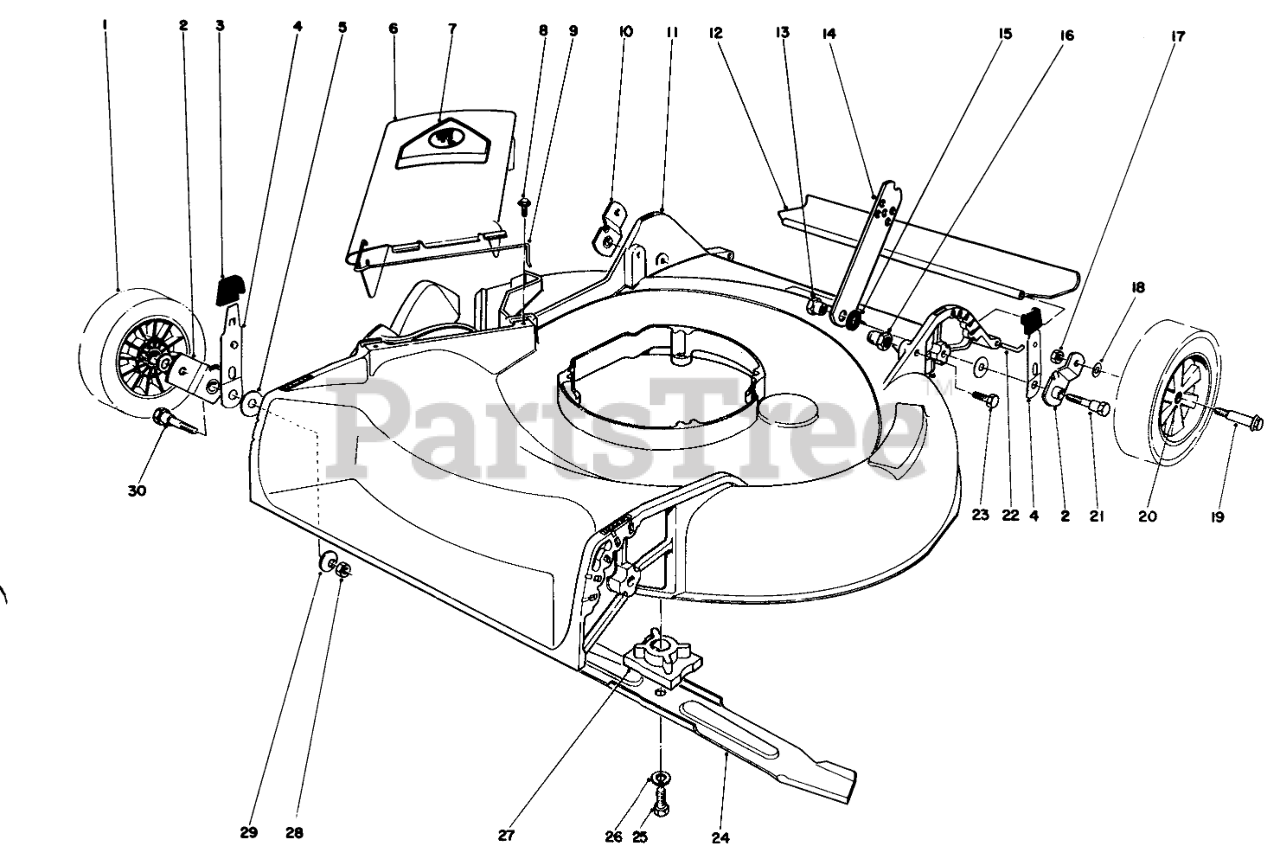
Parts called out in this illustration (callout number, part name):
1	Wheel & Tire Assembly (Incl. Ref. #20)
2	Pivot Arm
3	KNOB-ARM
4	SPRING ARM ASM
5	WASHER-PIVOT
6	Deflector Assembly (Incl. Ref. #7 & 9)
7	DECAL-DANGER
8	SCREW-HWH
9	SPRING HINGE
10	Pivot Arm
11	HOUSING/DECAL
12	REAR SAFETY SHIELD 21
13	HANDLE PIVOT NUT
14	HANDLE LATCH
15	SPACER
16	HANDLE PIVOT NUT
17	Nut
18	WASHER
19	BOLT-WHEEL
20	BUSHING
21	PIVOT SCREW
22	SHIELD ROD
23	SCREW-HH
24	Blade
25	SCREW-HH
26	WASHER-LOCK
27	BLADE RETAINER
28	NUT-LOCK, NI
29	WASHER-BELLEVILLE
30	5/16-18 PIVOT SCREW
